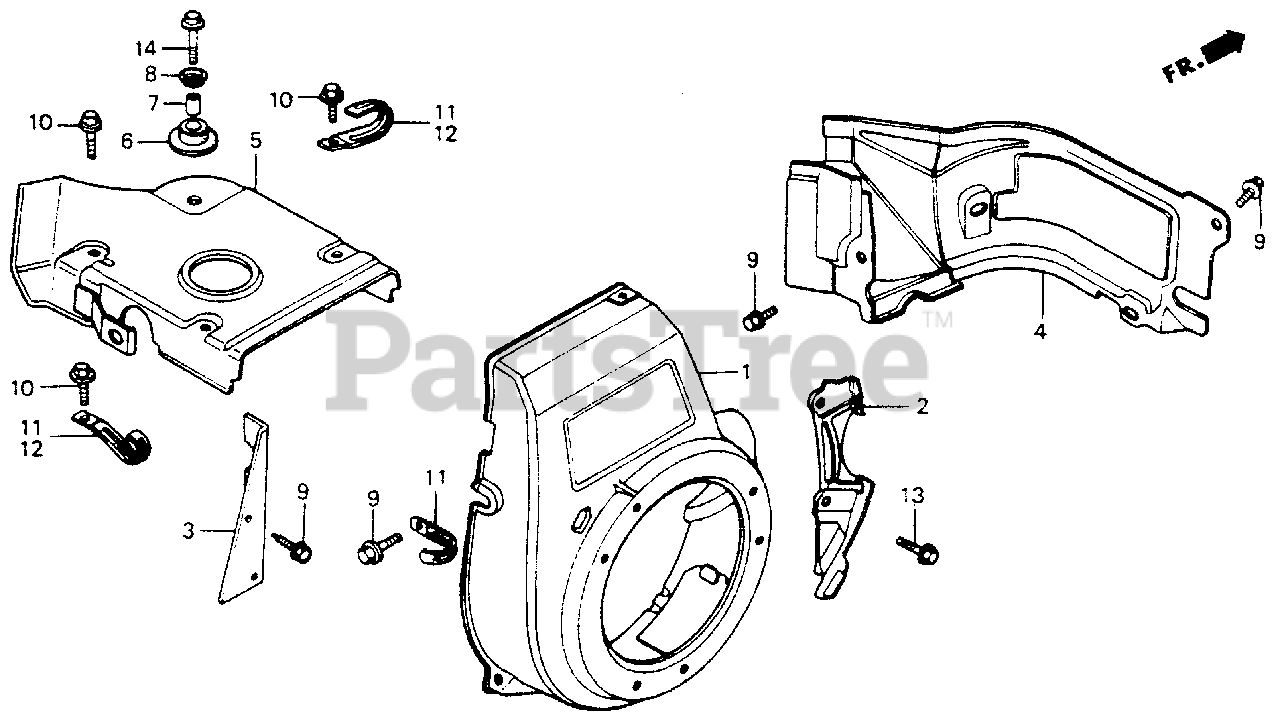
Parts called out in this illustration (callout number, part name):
1	COVER, FAN *R8* (BRIGHT RED)
2	PLATE, SIDE
3	GUIDE, AIR
4	SHROUD *R8* (BRIGHT RED)
5	COVER, TOP *R8* (BRIGHT RED) (NOT AVAILABLE)
6	RUBBER, STOPPER
7	COLLAR, DISTANCE
8	PLATE, STOPPER
9	BOLT, FLANGE (6X12) (CT200)
10	BOLT, FLANGE (6X14)
11	CLIP (2X50)
12	CLIP, WIRE HARNESS
13	BOLT, FLANGE (8X20)
14	BOLT, FLANGE (8X32)
